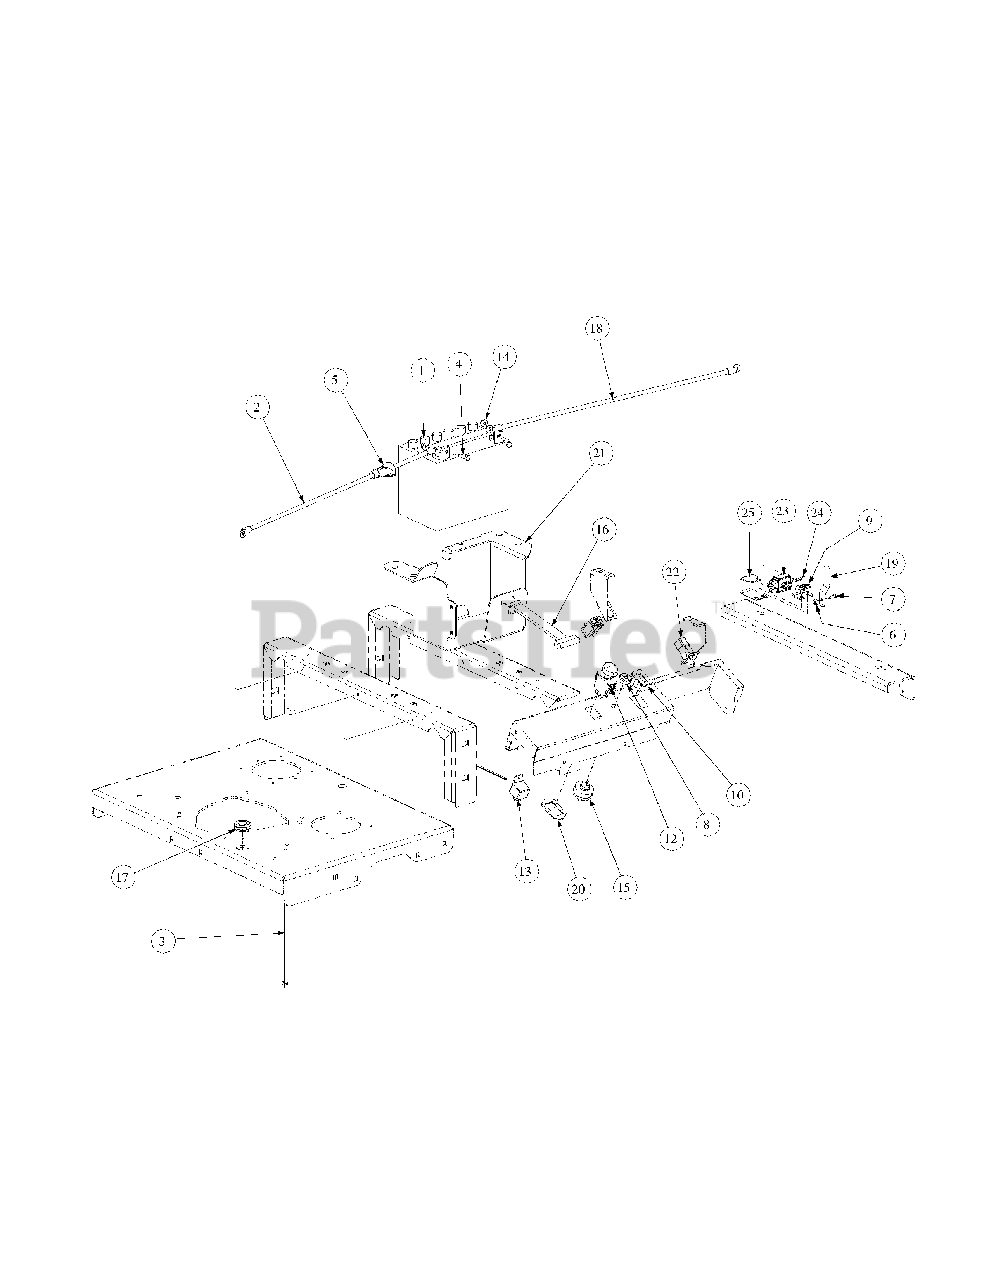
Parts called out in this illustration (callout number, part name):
1	Battery, 12V 225CCA 30 Min
2	Cable, Battery, Red, 36"
3	Tie, Cable, 3/16 x .05 x 7.4"
4	Screw, Hex, Cap, 1/4-20 x .75
5	Boot, 1" OD Rubber Battery-PST, Red
6	Lock Nut, Nylon Insert
7	Screw, Phillips Head, Machine, 10-32 x 5/8
8	Nut, W/Cap, 5/8-32 Ignition
9	Screw, TT, 1/4-20, 0.5, Hex Index Washer
10	Meter, Hour (Honda)
11	Hourmeter, Harness
12	Switch, Electric, PTO
13	Relay, 12V 40A
14	Lock Nut, 1/4-20
15	Switch, Ignition, 6 Pin
16	Strap, Battery
17	Grommet, .75 ID
18	Cable, Battery Red, 28"
19	Spring Retainer
20	Bracket, PTO Switch Retainer
21	Mount Bracket, Battery
22	Switch, Safety N.O./N.C.
23	Switch, Plunger
24	Bracket, Plunger Switch
25	Clamp, Plunger Switch
26	Harness Assembly
